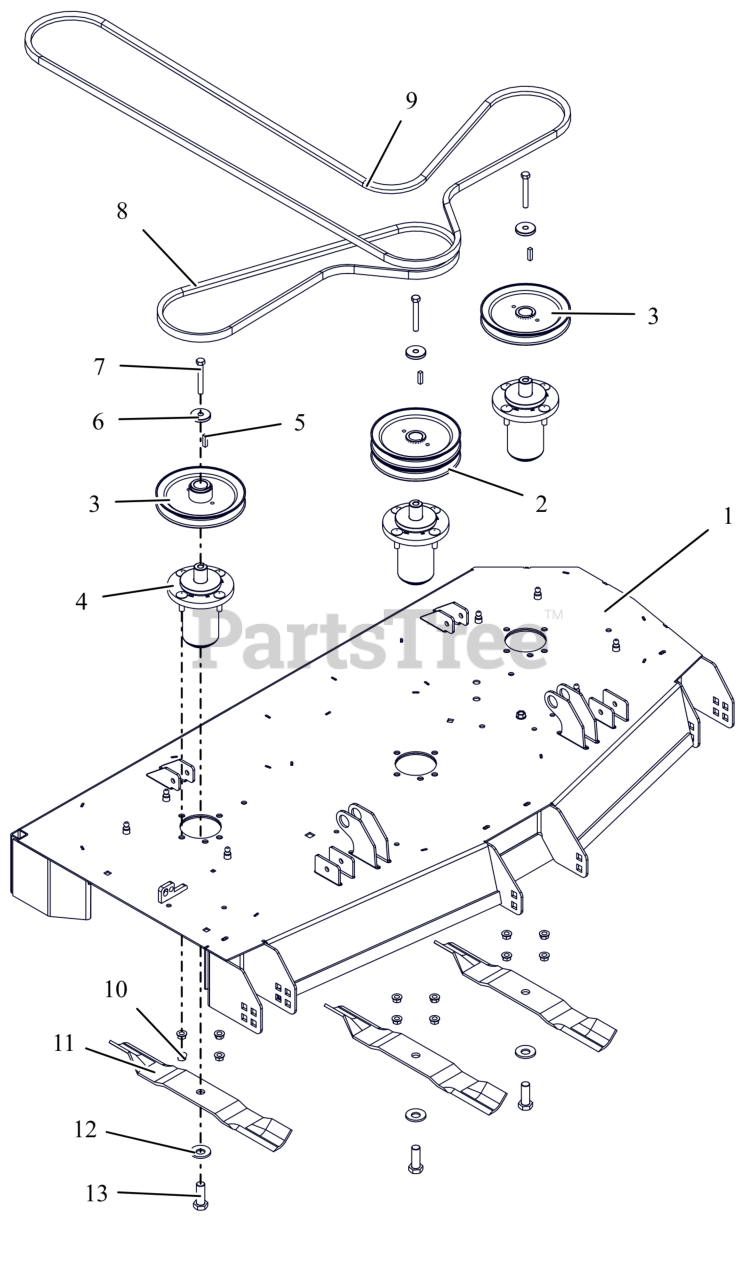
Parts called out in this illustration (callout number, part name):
1	KIT-DECK -52 W/DECALS XF3 BLK
2	PULLEY, DOUBLE 1.000 ID X 6.750 OD
3	PULLEY, V-1" ID X 6.75 OD
4	ASM, MAINT FREE ALUM SPINDLE
5	KEY, SQ .25X.25X1.00 RC 40-50
6	RETAINER, SHEAVE
7	BLT, HEX .38-16X2.75 G8 ZCC
8	V-BELT, B-COGGED
9	V-BELT, HB SECTION
10	NUT-LK-CTR-FLG .375-16 GF ZCC
11	BLADE, 18"
12	WSHR-BLVL .669X1.535X.138
13	BLT, HEX .62-18X1.75 G8 ZCC
